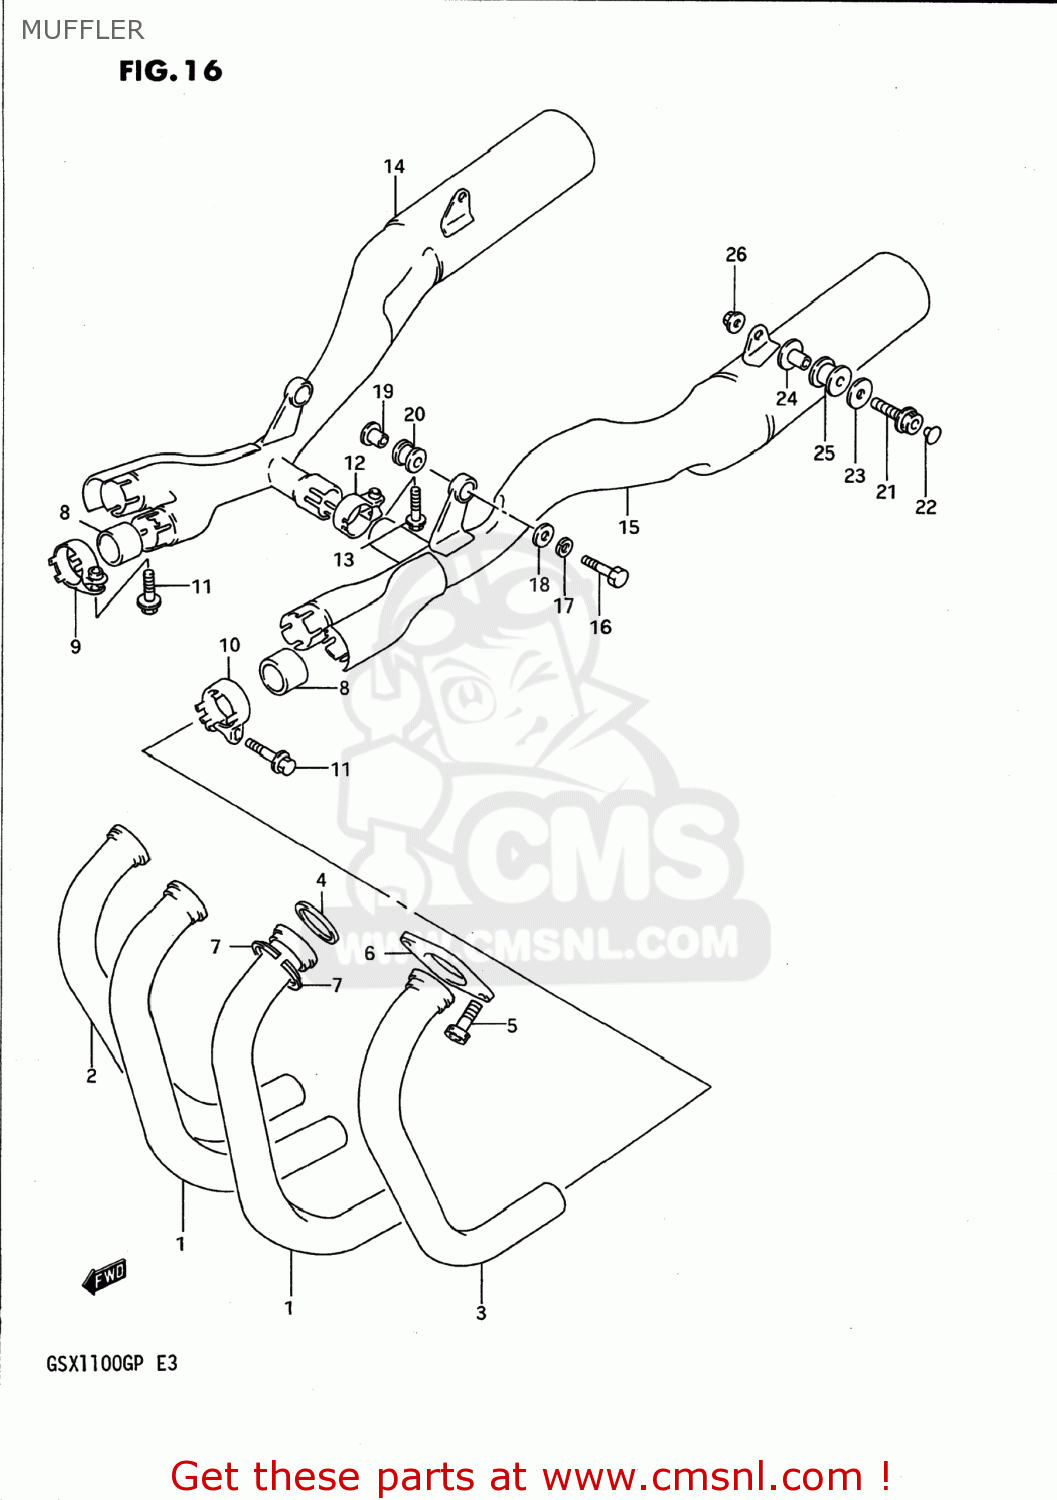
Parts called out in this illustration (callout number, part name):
1	PIPE,EXHAUST,CENTER
2	PIPE,EXHAUST
3	PIPE,EXHAUST
4	GASKET,EXHAUST (NAS)
5	BOLT, FRONT LH
6	CLAMP,EXHAUST PIPE
7	PLATE,EXHAUST PIPE
8	CONNECTOR,MUFFLER
9	CLAMP,MUFFLER CONNECTOR
10	CLAMP,MUFFLER CONNECTOR
11	BOLT
12	CLAMP,MUFFLER JOINT
13	BOLT
14	MUFFLER ASSEMBLY
15	MUFFLER ASSEMBLY
16	BOLT 8X45
17	LOCK WASHER
18	WASHER (8.5X20X1.6)
19	SPACER(8.6X12X18.5)
20	CUSHION
21	BOLT
22	CAP(OD:10)
23	WASHER (8.5X30X2.3)
24	SPACER(8.6X12X27.1)
25	CUSHION
26	NUT
